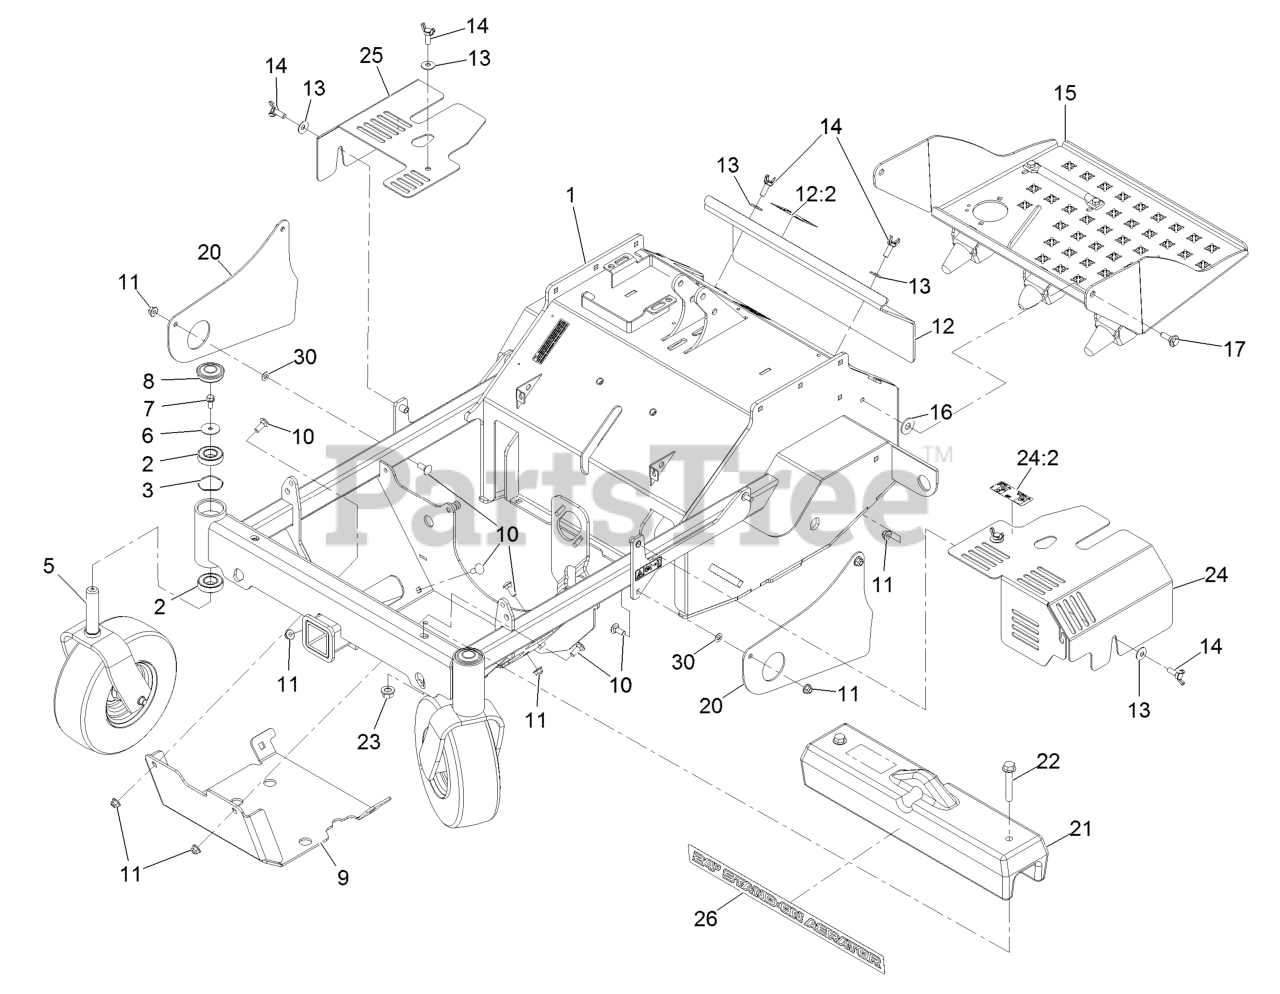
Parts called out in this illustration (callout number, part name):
1	Main Frame ASM
2	Bearing-Ball
5	Front Caster ASM
6	Washer-Flat
7	Screw-HH Flg 5/16-18 X 3/4
8	Cap-Grease
9	Guard-Engine
10	Bolt-Carriage 3/8-16 X 1
11	Nut-Nyloc 3/8-16 Flg
12	Access Cover ASM
12:2	Decal-Operation, Tine Ground (CE)
13	Washer-Spring Disc
14	Screw-Thumb
15	Platform ASM
16	Washer
17	Screw-Shoulder 3/8-16 1.295
20	Guard-Chain
21	Weight-Front
22	Screw-HF
23	Nut-Lock 1/2-13
24	Hydro-Cover
24:2	Decal-Release, Drive
25	Cover-Hydro
26	Decal-Standon Aerator 24
30	Washer-Thrust
